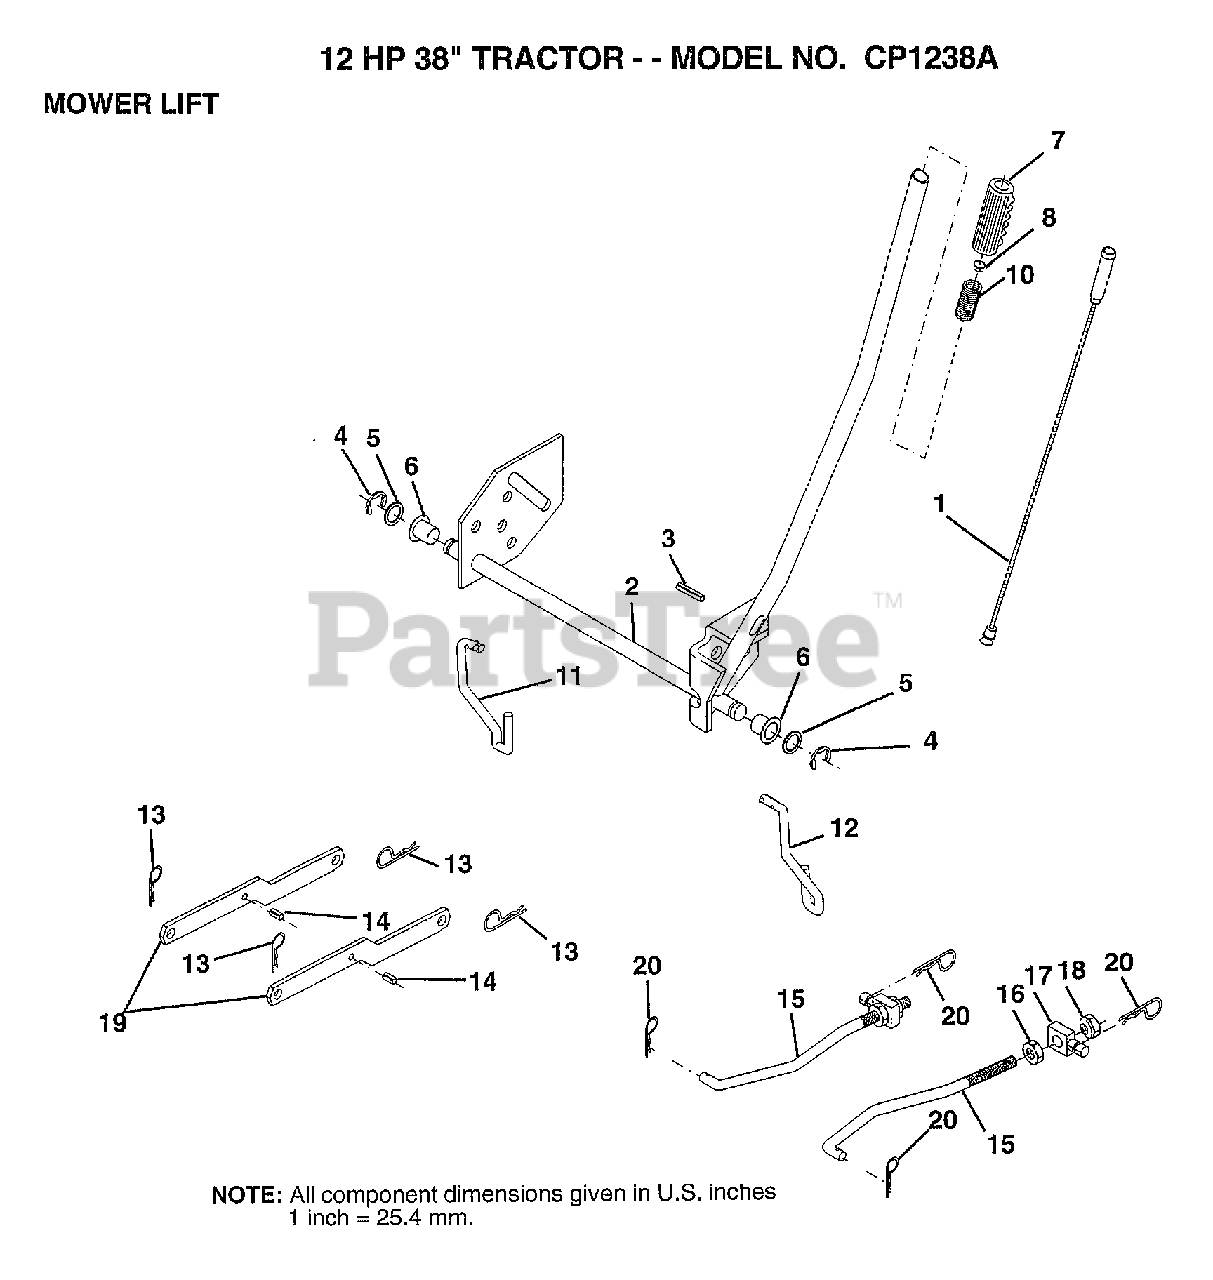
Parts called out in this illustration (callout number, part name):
1	WIRE ASM
3	PIN-GROOVE LT
5	WASHER
6	NYLON BEARING
7	GRIP
11	LINK LIFT LH
12	LIFT LINK RH
14	"PIN,SPRING"
15	LINK.FRONT
16	NUT
17	TRUNION
18	NUT.LK.W/WSH.1/2.
20	RETAINER.SPRING
